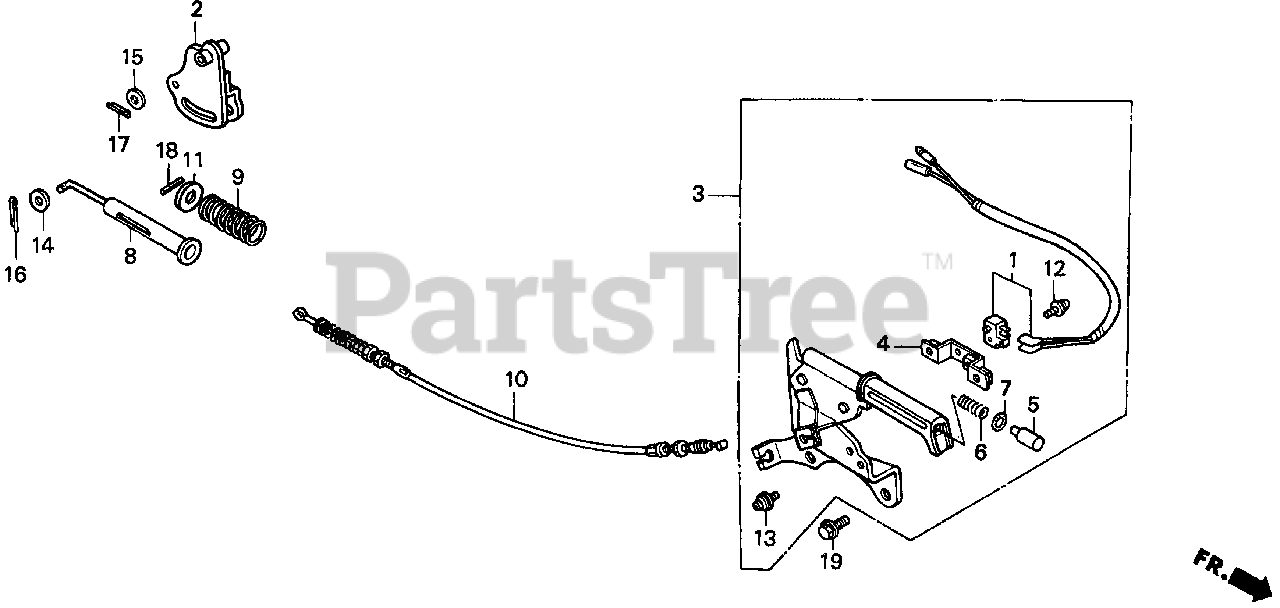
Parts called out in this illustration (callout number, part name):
1	SWITCH ASSY., PARKING BRAKE (NOT AVAILABLE)
1	SWITCH ASSY., PARKING BRAKE
2	ARM, BRAKE
3	LEVER ASSY., PARKING BRAKE (NOT AVAILABLE)
3	LEVER ASSY., PARKING BRAKE *YR161* (ORANGE)
4	BRACKET, PARKING BRAKE SWITCH
5	KNOB, PUSH ROD *YR161* (ORANGE)
6	SPRING, PUSH ROD
7	O-RING, PARKING BRAKE LEVER
8	PIPE, PARKING BRAKE SPRING SETTING
9	SPRING, PARKING BRAKE LOAD SETTING
10	CABLE, PARKING BRAKE
11	WASHER, BRAKE SPRING SETTING
12	SCREW-WASHER (4X14)
13	SCREW-WASHER (5X12)
14	WASHER, PLAIN (5MM)
15	WASHER, PLAIN (10MM)
16	PIN, COTTER (2.0X15)
17	PIN, COTTER (2.0X35)
18	PIN, SPRING (6X25)
19	BOLT, FLANGE (8X16)
